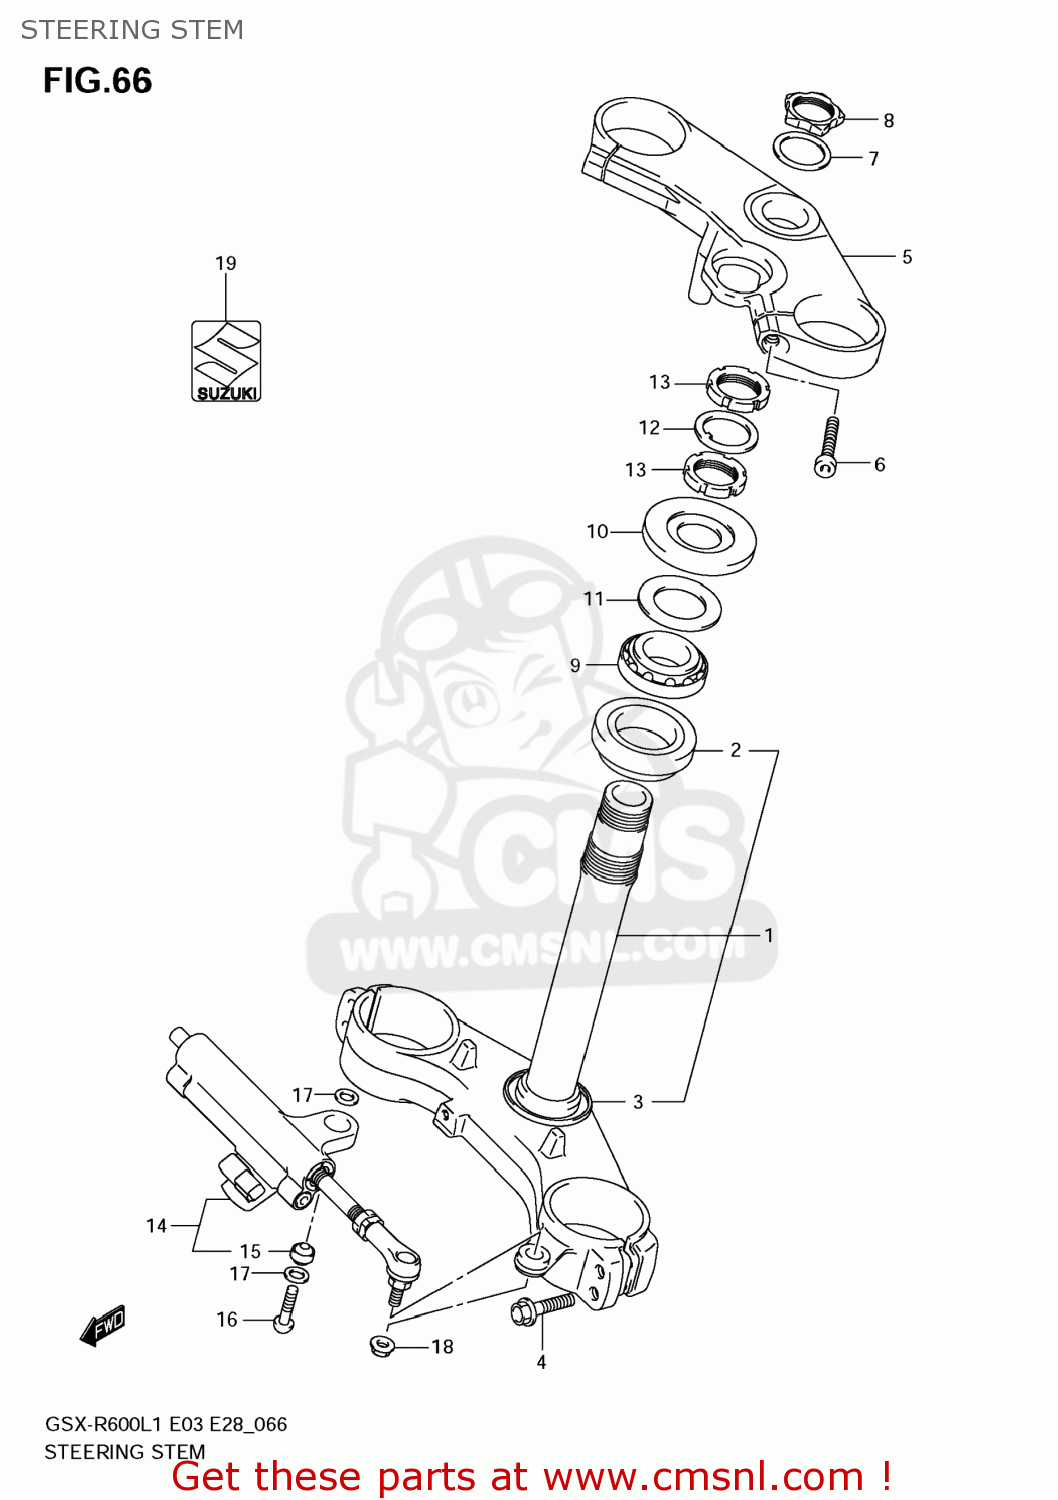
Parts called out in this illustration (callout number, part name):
1	STEM,STEERING
2	BEARING(30X55X17)
3	SEAL,STEERING LWR
4	BOLT,HOLDER AXLE(8X40)
5	HEAD,STEERING STEM
6	BOLT,HOLDER(8X25)
7	WASHER,STEM HEAD
8	NUT,STEM HEAD
9	BEARING(30X55X17)
10	COVER,STEERING UPR
11	SEAL,STEERING LWR
12	WASHER,STEERING STEM
13	NUT,STEERING STEM
14	DAMPER ASSY,STEERING
15	BEARING(8X17.5X11)
16	BOLT(8X35)
17	SEAL,PILLOW BALL,DUST
18	NUT
19	EMBLEM,S
